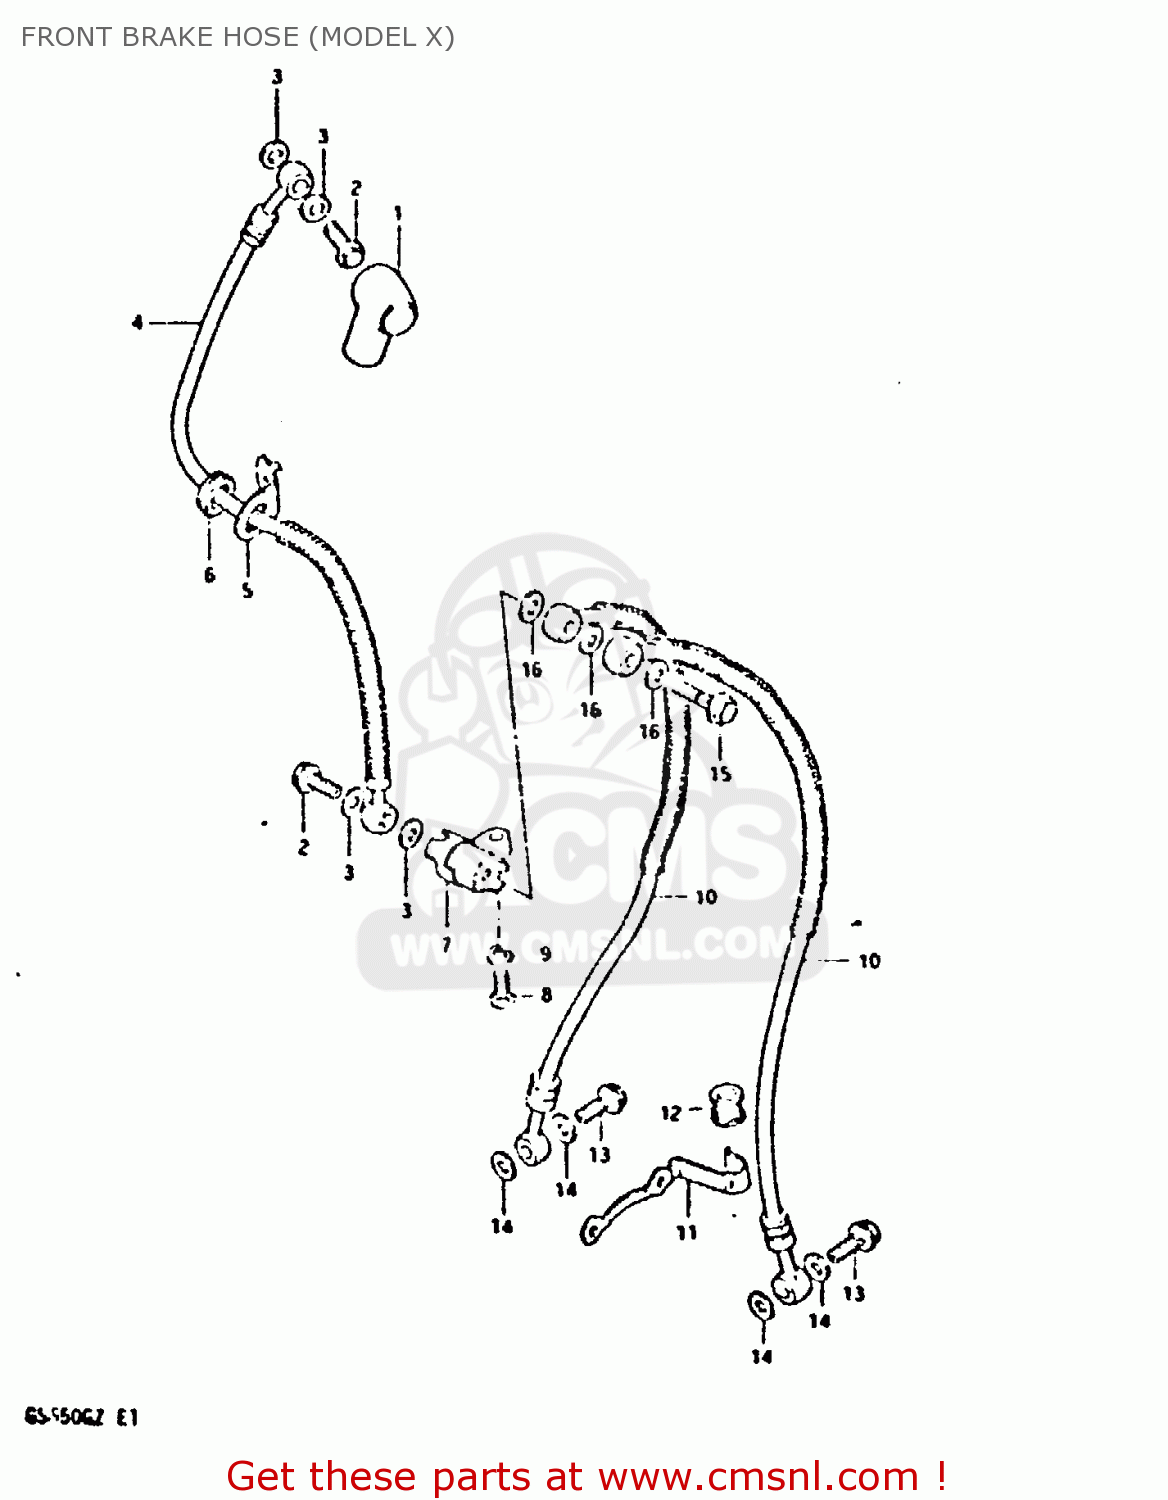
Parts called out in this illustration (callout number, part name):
1	BOOT,MASTER CYLINDER
2	BOLT,UNION
3	WASHER
4	HOSE, BRAKE NO.1 (FOR NEUTRAL HANDLEBAR)
5	GUIDE,BRAKE HOSE NO.1
6	GROMMET
7	JOINT,BRAKE HOSE
8	BOLT
9	LOCK WASHER
10	HOSE,FRONT BRAKE
11	GUIDE,BRAKE HOSE NO.2
12	BUSH,BRAKE HOSE GUIDE,NO.2
13	BOLT,UNION
14	WASHER
15	BOLT,UNION
16	WASHER
